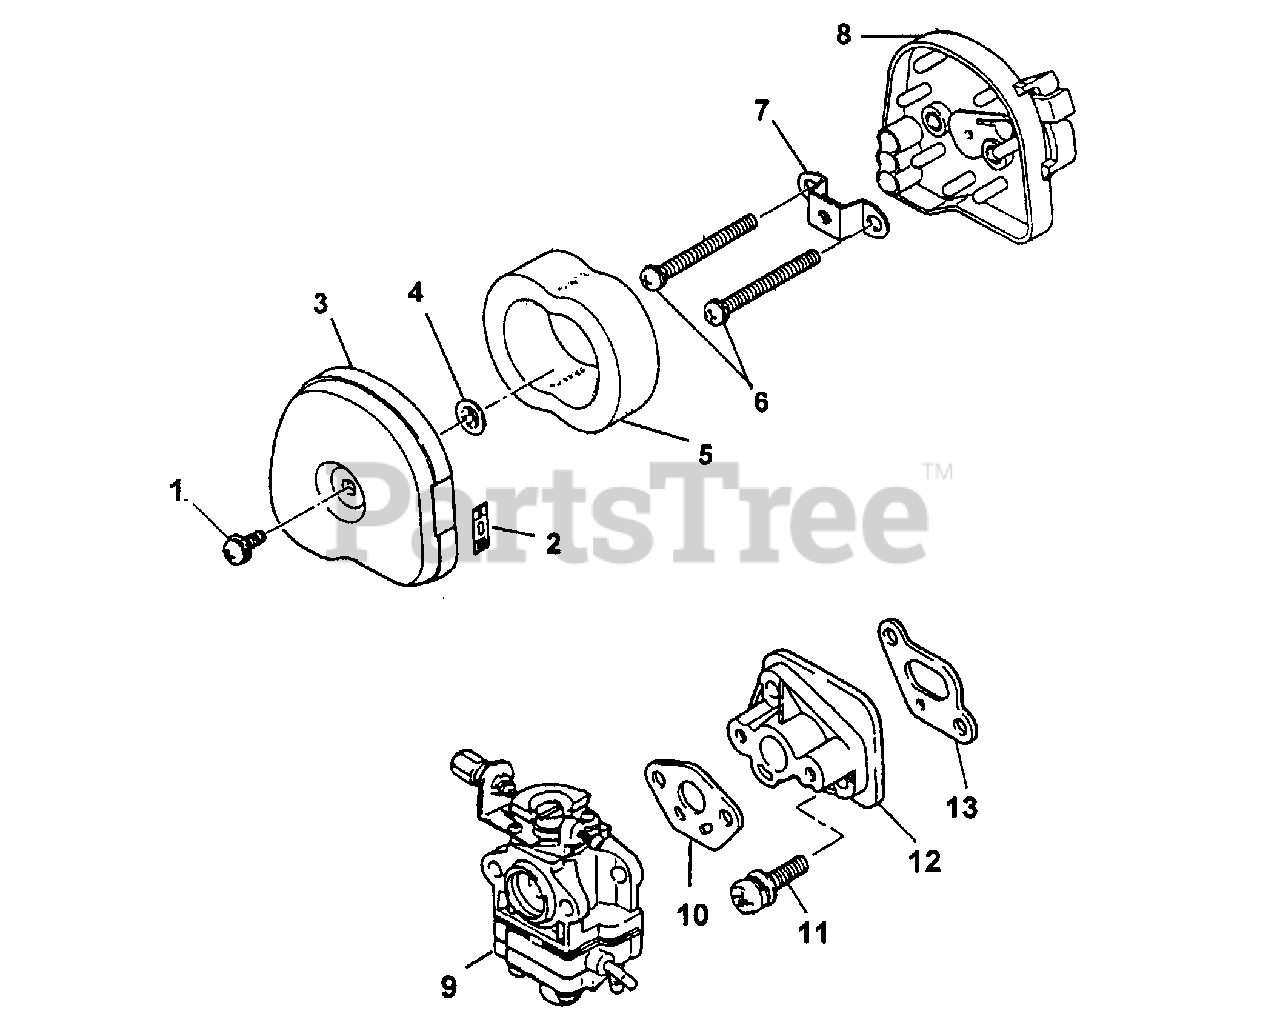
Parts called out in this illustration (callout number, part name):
1	SCREW & WASHER
2	LABEL, CHOKE
5	ELEMENT
6	SCREW & WASHER
7	BRACKET
9	CARBURETOR
10	GASKET, CARB
11	SCREW & WASHER
12	INSULATOR
13	GASKET, INSULATOR
